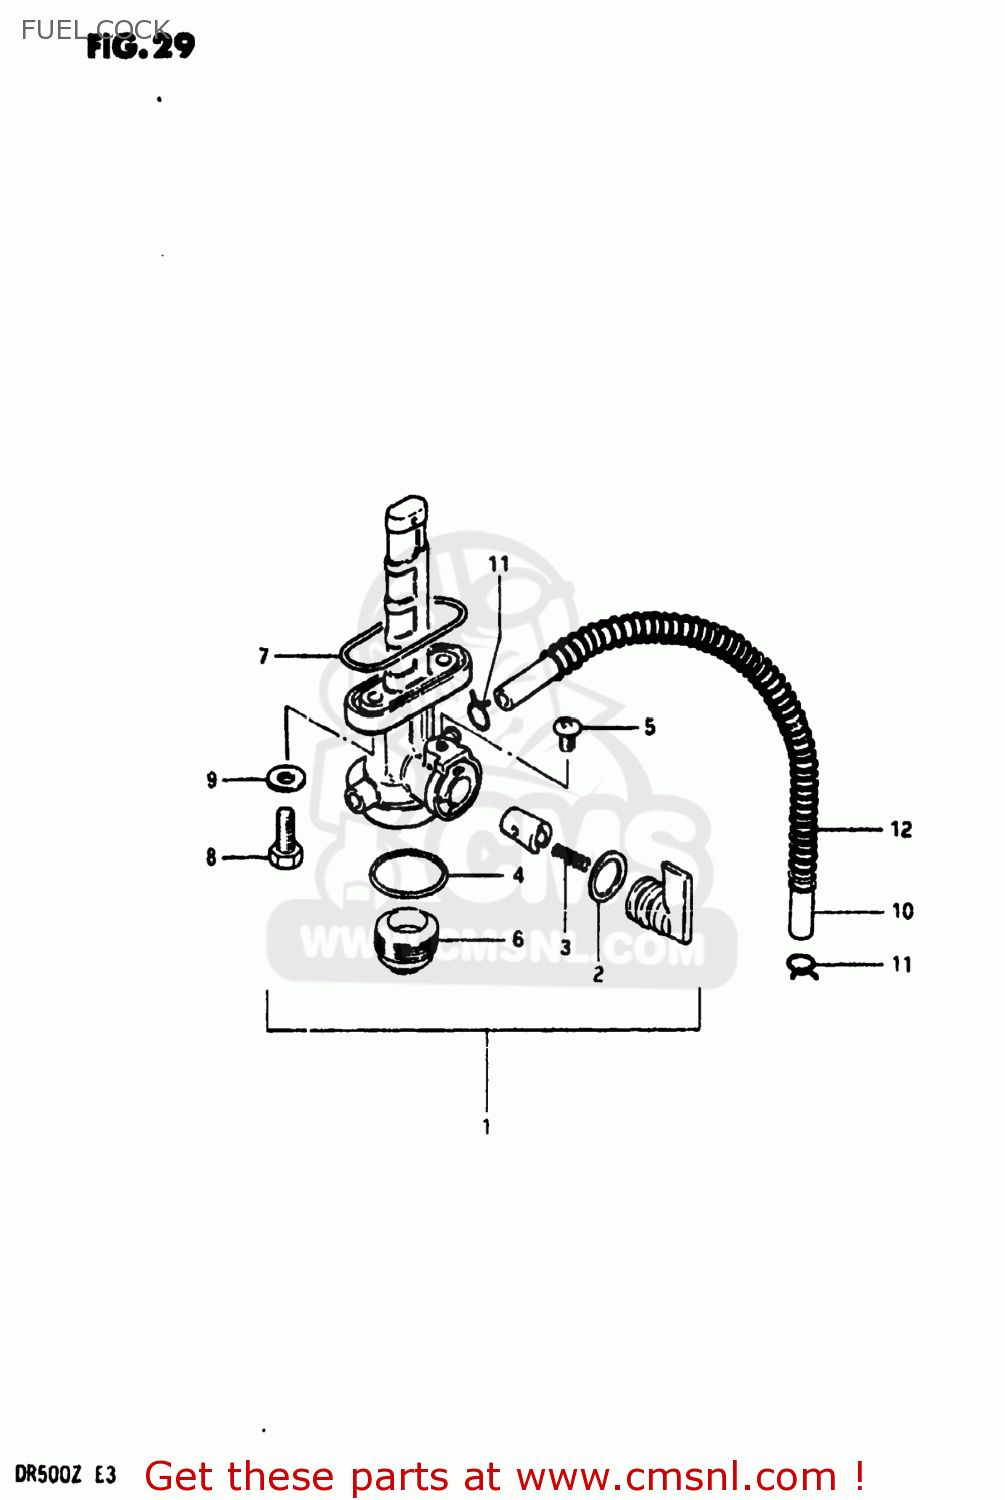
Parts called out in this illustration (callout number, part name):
1	COCK ASSEMBLY,FUEL
2	O-RING
3	SPRING
4	GASKET,FILTER (NAS)
5	SCREW,FUEL COCK LEVER
6	CUP,STRAINER
7	O RING,FUEL COCK
8	BOLT(6X20)
9	GASKET
10	HOSE
11	CLIP
12	SPRING
